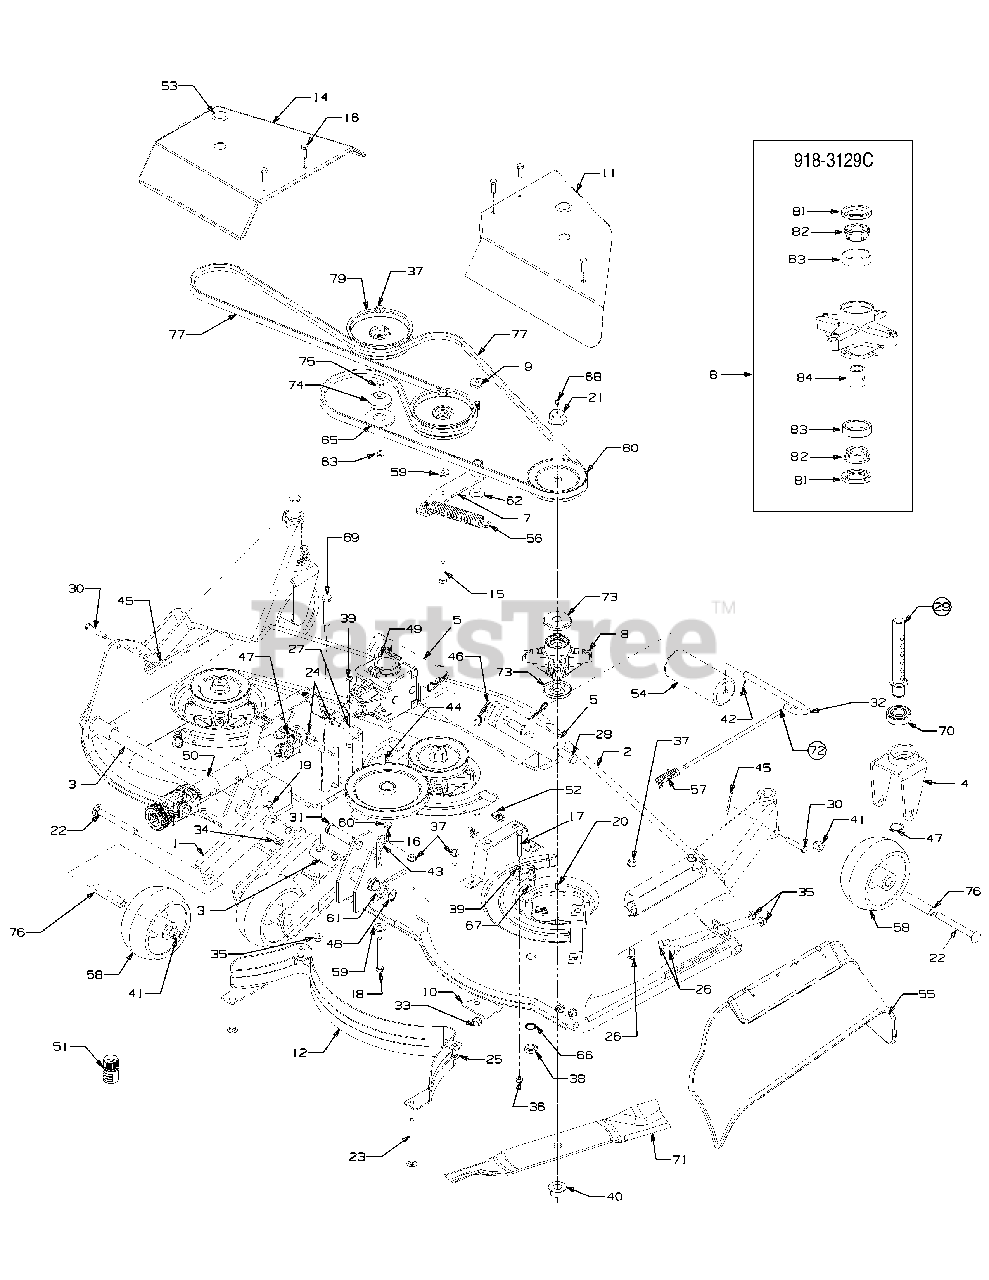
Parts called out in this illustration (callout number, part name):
1	BRACKET, DECK WHEEL
2	DECK HOUSING
3	HANDLE, WHEEL HEIGHT ADJUSTMENT
4	BRACKET, CASTER WHEEL YOKE
5	LINK, FRONT LIFT
6	GUARD, DECK
7	BRACKET, IDLER
8	SPINDLE ASSEMBLY
9	BOLT ASSEMBLY, SHOULDER
10	PLATE, IDLER SUPPORT
11	COVER, BELT RH
12	BAFFLE, DECK
13	BRACKET, CHUTE DEFLECTOR
14	COVER, BELT LH
15	SCREW, HEX CAP, 3/8-19 X 1.75 GR5
16	SCREW, HEX CAP, 5/16-18 X 1/0 GR5
17	SCREW, HEX CAP, 5/16-18 X 2.25 GR5
18	SCREW, HEX CAP, 3/8-16 X 3.0 GR8
19	SCREW, HEX CAP, 5/16-18 X 1.5 GR5
20	SCREW, HEX WASH. HD TAPP 5/16-18 X .75
21	BOLT, SPINDLE, 3/4-16 X 4.25
22	SCREW, CARRIAGE 1/2-13 X 4.5 GR5
23	SCREW, CARRIAGE 3/8-16 X 4.50 GR5
24	SCREW, HX PATCH, 5/16-18 X .75 GR5
25	BOLT, CARRIAGE, 3/8-16 X 1.0
26	BOLT, CARRIAGE, 3/8-16 X .75
27	SCREW, SOCKET HD, 5/16-18 X 1.75 GR5
28	PIN, CLEVIS, .625 X 1.5
29	SHAFT, GAUGE WHEEL
30	PIN, CLEVIS, 3/8 X 2.015
31	PIN, CLEVIS, 3/4 X 2.5
32	PIN, ROLLER, 1/2 X 7.31
33	NUT, HEX LOCK, 7/16-14
34	NUT, HEX INSERT FLANGE LOCK, 5/16-18 GR5
35	NUT, HEX INSERT FLANGE LOCK, 3/8-16 GRF
36	NUT, HEX INSERT LOCK, 5/16-18 GR5
37	NUT, HEX FLANGE LOCK, 3/8-16 GRF
38	NUT, HEX, M16-1.5
39	NUT, HEX JAM LOCK, 5/16-18
40	NUT, HEX FLANGE LOCK, 3/4-16 GR8
41	NUT, HEX INSERT LOCK, 1/2-12 GRB
42	PIN, COTTER, 1/8 X 1.0
43	PIN, INTERNAL COTTER
44	KEY, SQUARE, 1/4 X 1.0
45	PIN, INTERNAL COTTER
46	PIN, INTERNAL COTTER
47	RING, SNAP
48	RING, EXTERNAL RETAINING
50	SHAFT, DECK DRIVE
50	Repair Kit, Yoke Lock
51	ADAPTER, NOZZLE
52	NUT, SPEED, 5/16-18
53	BUTTON, PLUG
54	ROLLER, FRONT
55	DEFLECTOR, CHUTE
56	SPRING, EXTENSION, 1.0 X 6.14
57	SPRING, TORSION
58	WHEEL, CASTE
59	WASHER, FLAT, .385 X 1.0 X .135
60	WASHER, FLAT, .344 X .688 X .065
61	WASHER, FLAT, .88 X 1.38 X .125 HT
62	WASHER, FLAT, .45 X 1.25 X .164 HT
63	WASHER, FLAT, .39 X .75 X .105
64	WASHER, FLAT, 033 X 1.25 X .06 HT
65	WASHER, FLAT, 1.063 X 2.5 X .16
66	WASHER, LOCK
67	NOZZLE, DECK WASH
68	FITTING, LUBE
69	BOLT, SHOULDER, .496 X 2.5:3/8-16
70	BEARING, BALL
71	BLADE, HIGH LIFT
72	ROD, CHUTE DEFLECTOR
73	SPACER, SPINDLE
74	SPACER, IDLER
75	SPACER, .38 X .625 X .21
76	AXLE, CASTER WHEEL
77	V BELT, B SECTION X 133
78	PULLEY, DRIVE
79	PULLEY, IDLER 5.0
80	PULLEY, SPINDLE
81	SEAL, OIL
82	BEARING, CONE
83	CUP, BEARING
84	SPACER, BEARING
